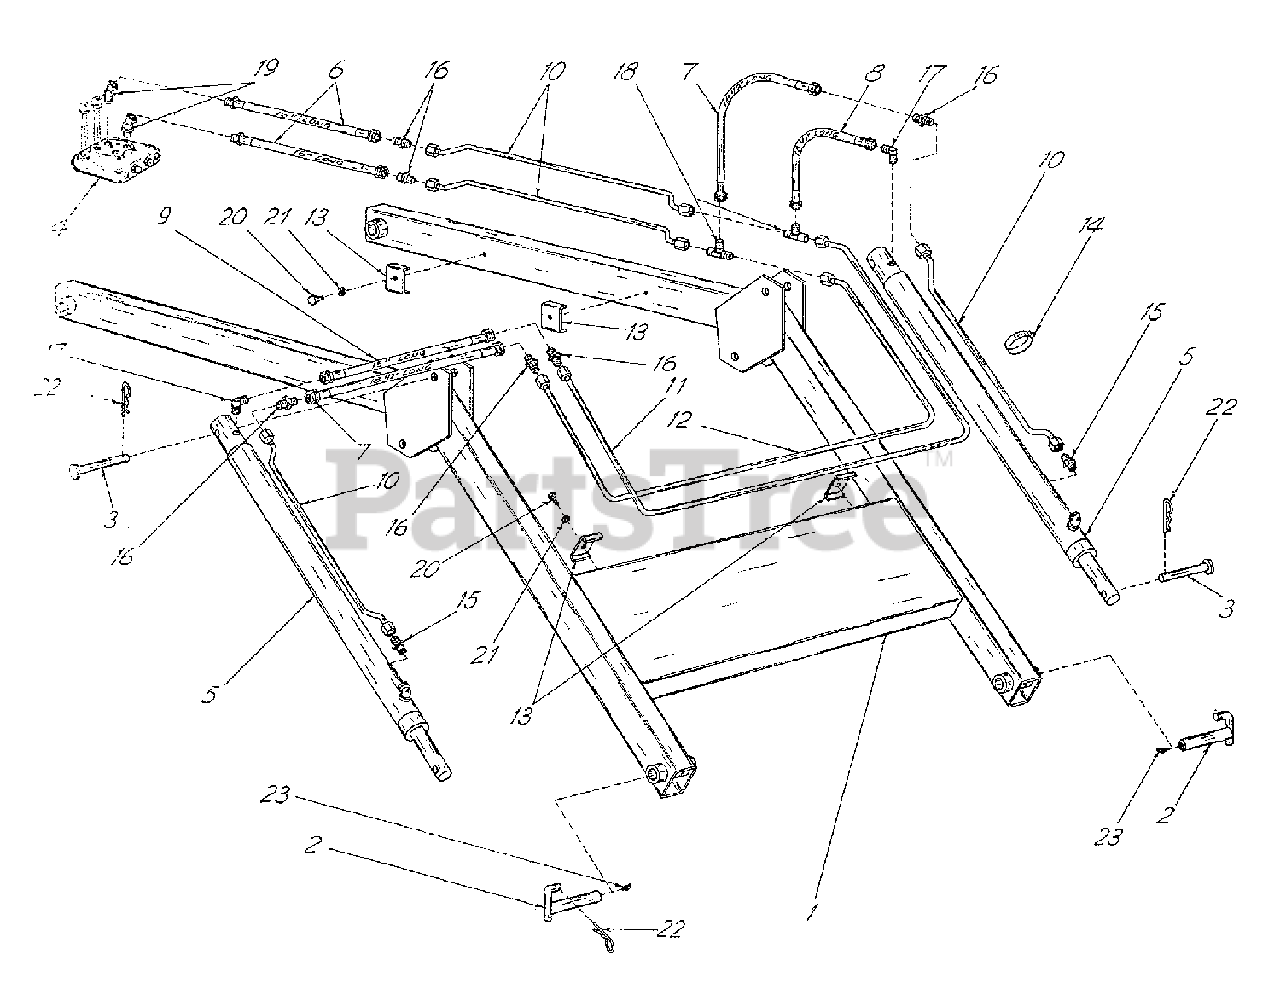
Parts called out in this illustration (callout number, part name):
1	WELDED ASSEMBLY, Lift
2	PIN, Lock
4	VALVE, Hydaulic
5	HYDRAULIC, Cylinder
6	HYDRAULIC, Hose, 1/4 ID x 16-1/2 " Long
7	HYDRAULIC, Hose, 1/4 ID x 18-1/2" Long
8	HYDRAULIC, Hose, 1/4 ID x 13-1/2" Long
9	HYDRAULIC, Hose, 1/4 ID x 15" Long
10	TUBE ASSEMBLY, Hydraulic
11	TUBE ASSEMBLY, Hydraulic
12	TUBE ASSEMBLY, Hydraulic
13	CLAMP, Tube
14	CLAMP, Hose
15	ADAPTER, Straight
16	ADAPTER, Straight
17	ELBOW ADAPTER, 90 Degrees
18	UNION TEE
19	UNION ADAPTER, 45 Degrees
20	BOLT, 5/16 NC x 3/4 Hex Head Capscrew
21	WASHER, 5/16 Lock
22	PIN, Hair, #3
23	FITTING, Grease, 45 Degrees
